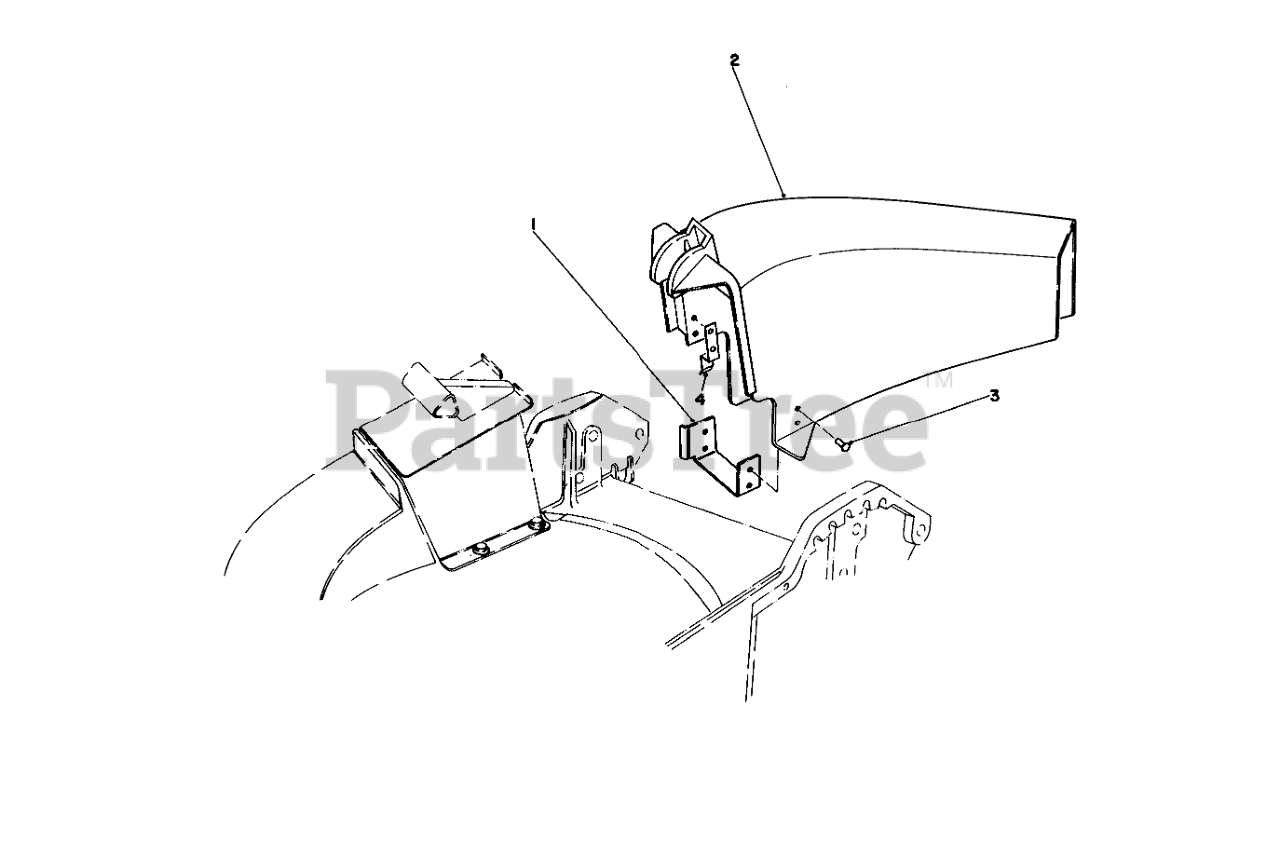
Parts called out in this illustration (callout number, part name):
1	CHUTE BRACKET
2	Chute Discharae
3	RIVET
4	CHUTE TAB
